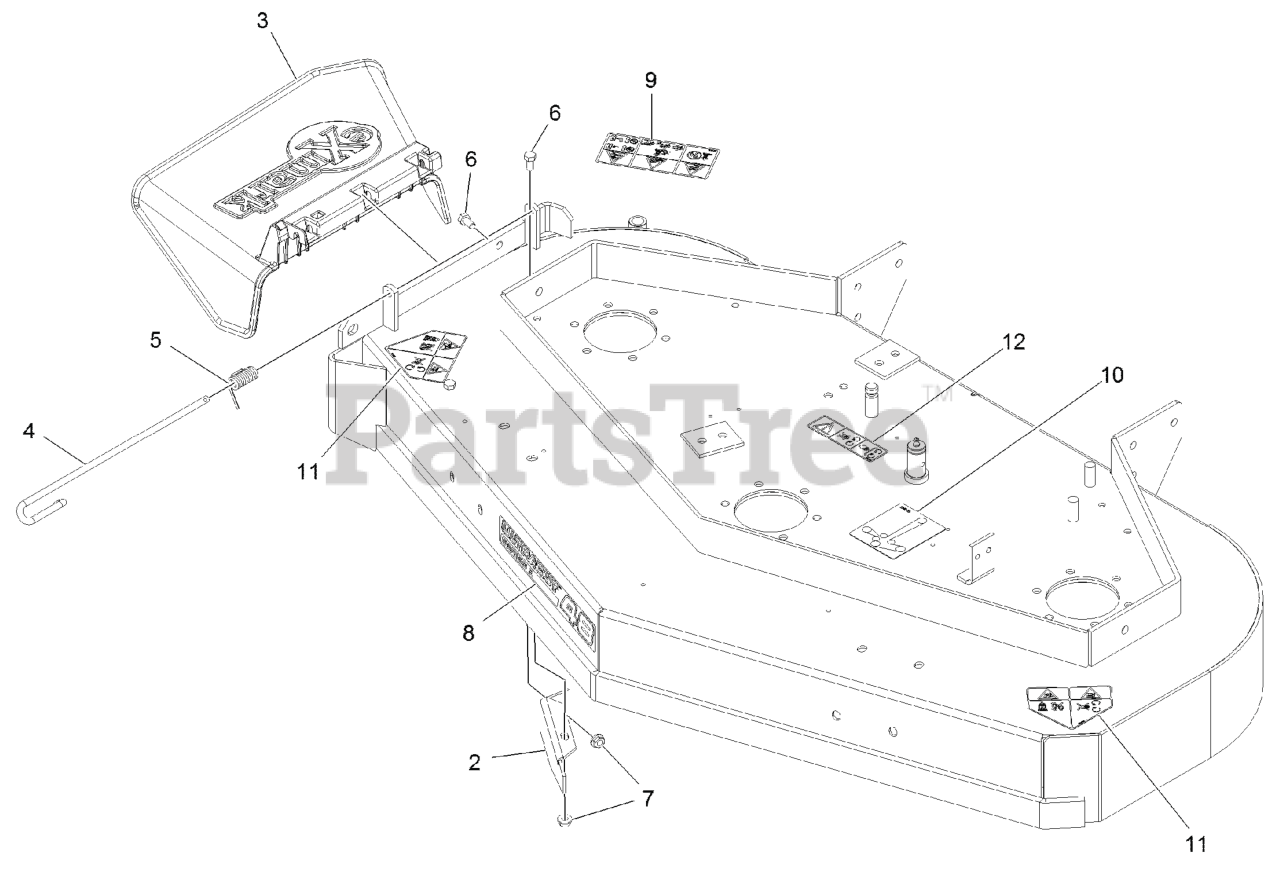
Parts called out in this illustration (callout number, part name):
2	BAFFLE-DOGLEG
3	CHUTE DEFLECTOR XRK M056
4	PIN-CHUTE
5	SPRING, TORSION
6	SCREW-HH
8	DECAL-ULTRACUT 48 SERIES
9	DECAL-WARNING THROWN OBJ
10	DECAL-ROUTING, BELT
11	DECAL-DANGER
12	DECAL-COVER, MISSING
